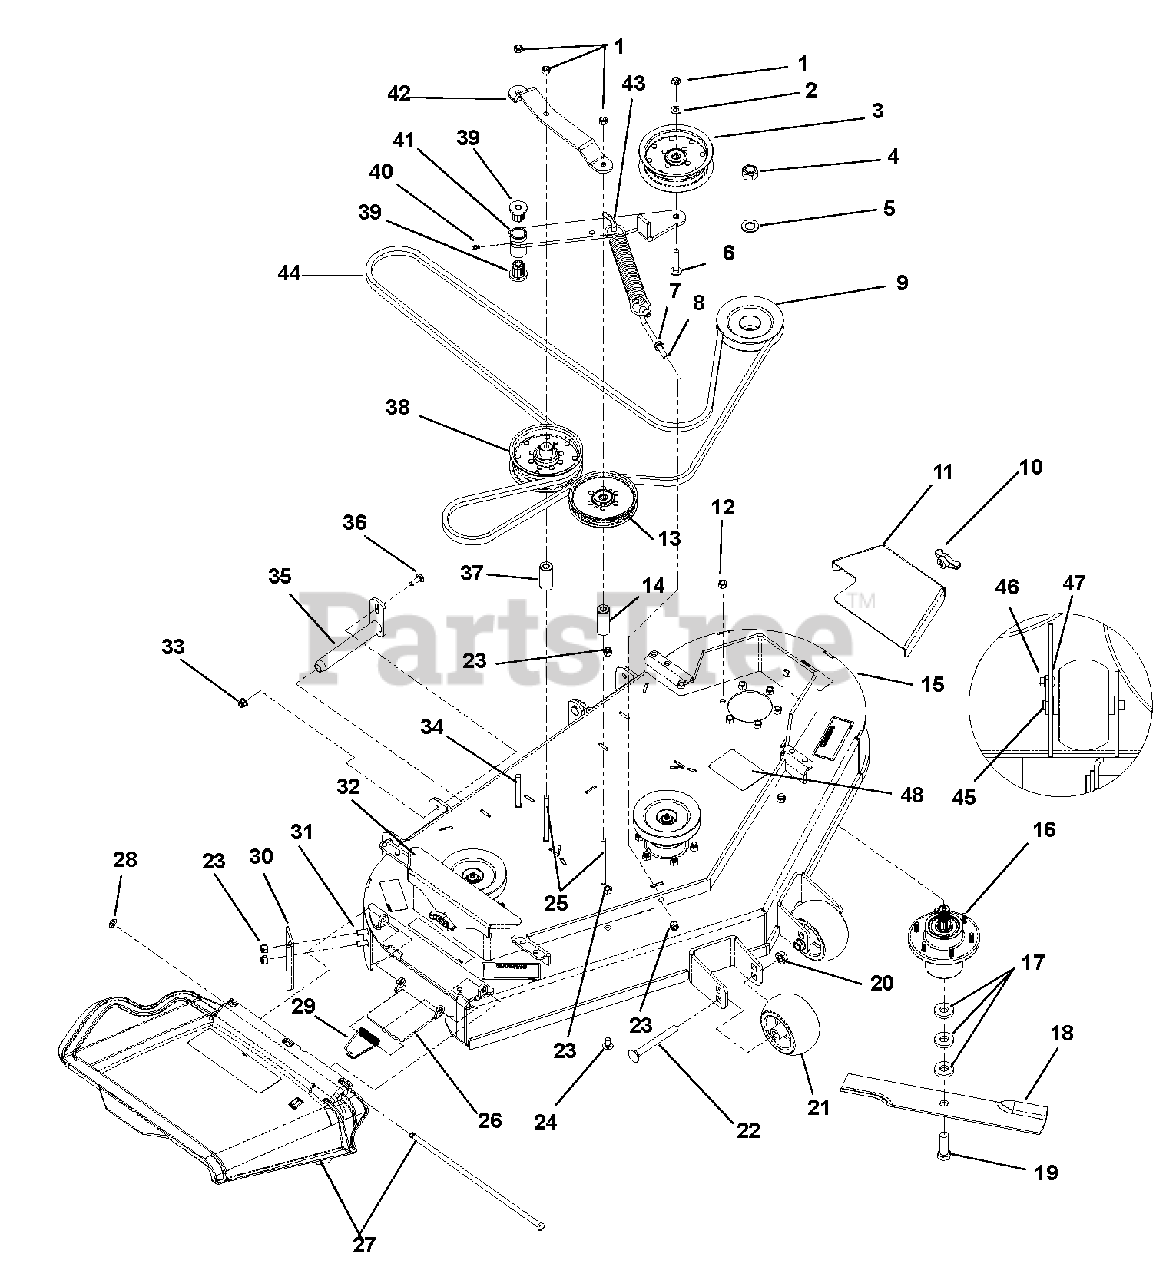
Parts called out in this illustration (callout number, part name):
1	LOCKNUT, 3/8-16 CROWN Y
2	WASHER, .406 X .813 X .065 FLAT Y
3	PULLEY, FLAT 5.0 X.38 W/BRG
4	LOCKNUT, 3/4-16 CROWN C
5	WASHER, .75X1.3125X .113
6	BOLT, 3/8-16X2.25 CRG 5 Y
7	LOCKNUT, 3/8-16 WHIZ Y
8	J-BOLT, 3/8-16 X 4.00 Y
9	PULLEY, SPLINE SPINDLE OFFSET
10	KNOB, LOCKING
11	WLDT, BELT COVER LH 48
12	NUT, 3/8-16 STD HEX GR5 Y
13	PULLEY, FLAT 5.00 X .375 W/BRG
14	SPACER, .437 X 1.00 X 2.50 SMLS
15	ASSY, 48 EVERRIDE DECK W/ DECALS
16	ASSY, SPINDLE HOUSING
17	WASHER, BLADE
18	BLADE, 16.50 LO-LIFT
19	BOLT, 5/8-11 X 2.00 HEX 8 Y
20	LOCKNUT 1/2 W/ FLANGE
21	WHEEL, GAGE
22	BOLT, 1/2-13X4.50 CRG 5 Y
23	LOCKNUT, 3/8-16 NYLOC Y
24	BOLT, 3/8-16 X 3/4 CAR GR5 LNNK
25	BOLT, CAR 3/8-16 X 5.00
26	BRACKET, CHUTE SUPPORT 48" DECK
27	CHUTE DISCHARGE ASST #
28	RETAINER #
29	SPRING, DISCHARGE CHUTE
30	PLATE, EXTENDER 48" HYDRO
31	BOLT, 3/8-16 X 1.00 CRG 5 SN Y
32	WLDT, BELT COVER RH 48
33	LOCKNUT, FL, ISO7043, M8X1.25
34	BOLT, 3/8-16X3.50 CRG 5 Y
35	PIN, WELDED
36	BOLT, RH, SQNECK, JDS137, M8X1.25X
37	SPACER, .437 X 1.00 X 2.25 SMLS
38	PULLEY, FLAT 5.25 X .375 W/BRG
39	BRG, FLG M1 X M25 X M27 FLUTED
40	FTG, 1/4-28 STRGT GREASE ZERK
41	ARM, IDLER
42	STRAP, IDLER PULLEY
43	SPRING, DECK IDLER
45	PIVOT, RETAINER WELD
46	NUT, 1/4" FLANGE PREVAILING TOR
47	BOLT, 1/4-20 X .750 CRG 5 Y
48	DECAL, BELT PATH
